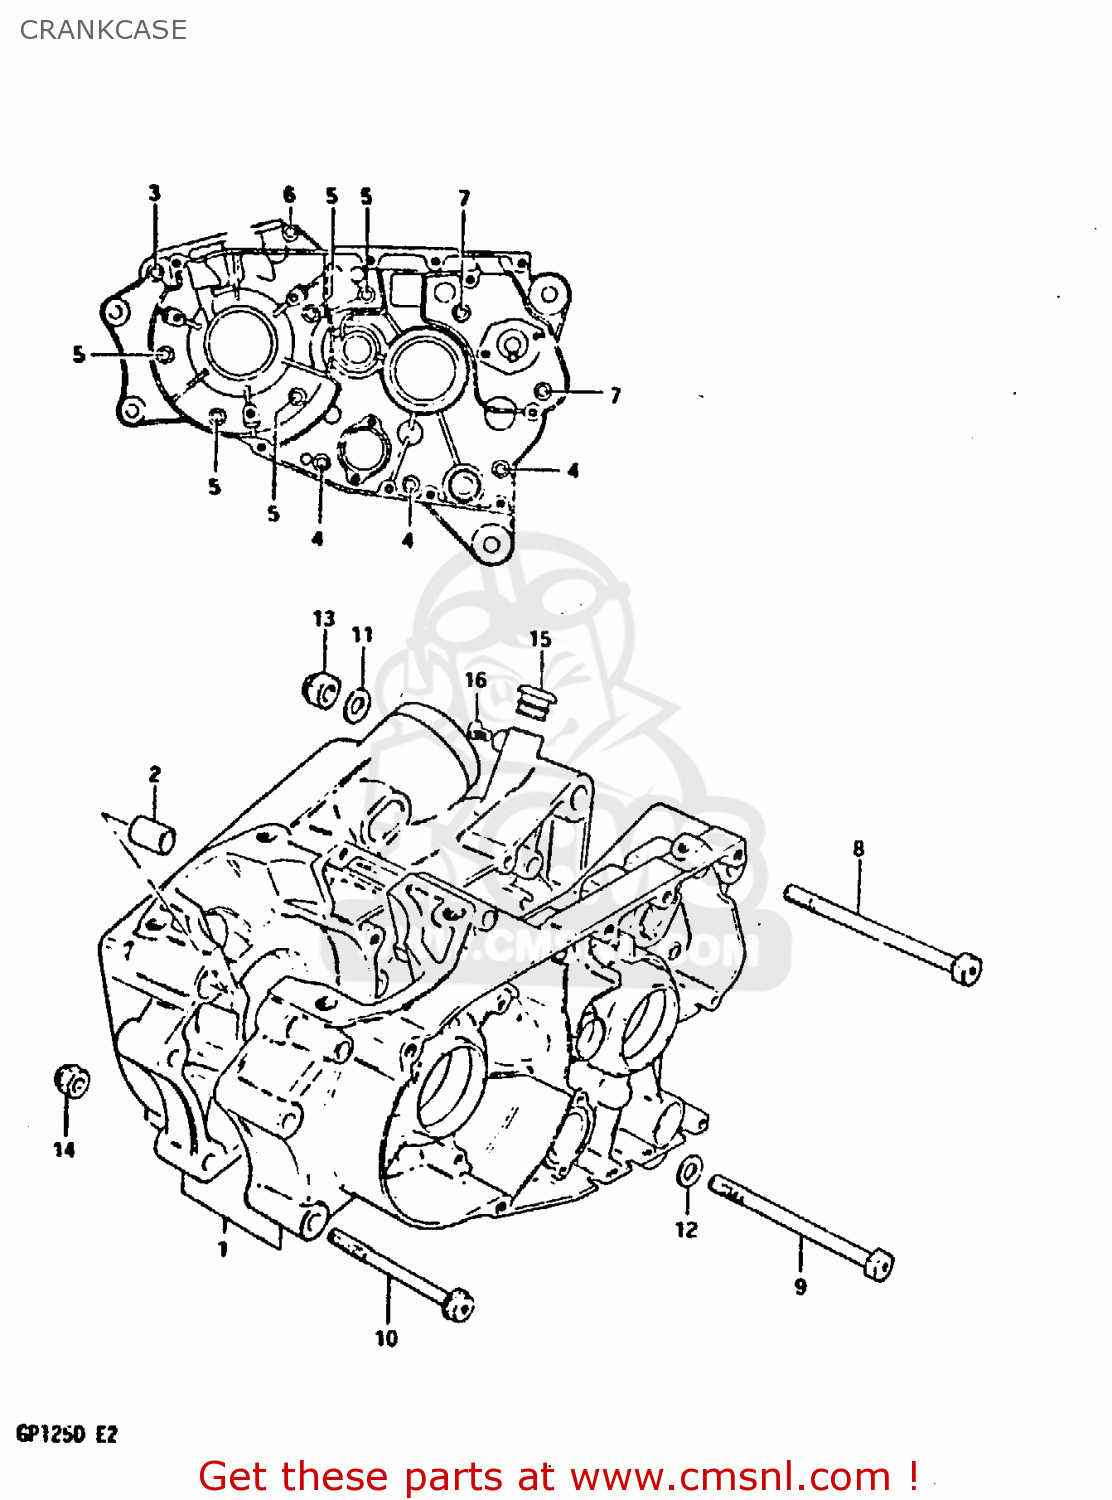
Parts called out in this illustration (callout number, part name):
1	CRANKCASE SET
2	PIN
3	SCREW 6X70
4	SCREW 6X65
5	SCREW
6	SCREW
7	SCREW (6X35)
8	BOLT 10X120
9	BOLT 10X115
10	BOLT 8X90
11	WASHER
12	WASHER(10.5X20X3.2)
13	NUT
14	NUT
